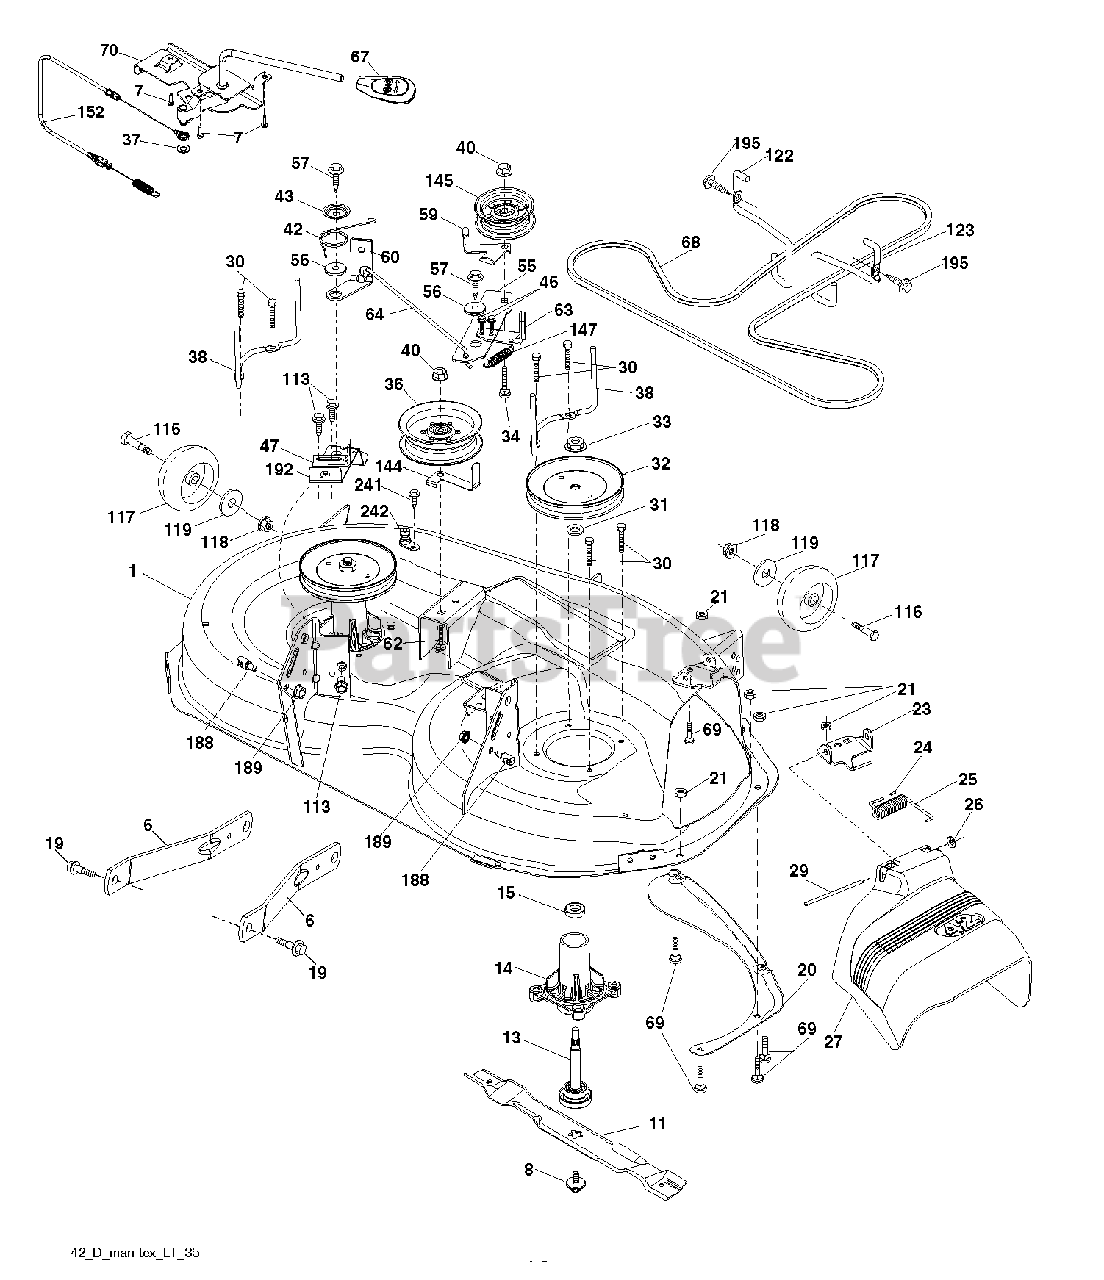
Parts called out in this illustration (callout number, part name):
1	DECK.WELDMENT.42"
6	ARM.SUSPENSION.MOWER.R
7	SCREW.#10 X 0.750.BOS THREAD
8	BOLT.WASHER.ASM.7/16-2
11	42" HI-LIFT BLADE
13	SHAFT.ASM.MDRL.N/GREASE.38
14	HOUSING MANDREL
19	BOLT.SHOULDER
20	BAFFLE.VORTEX
21	LOCKNUT
23	BRKT.DEFLECTOR.38"2005+
24	CAP-SLEEVE LT
25	SPRING.TORSION.DEFLECT
26	NUT PUSH M
27	SHIELD.DEFLECTOR.MOWER.42"BLAC
29	ROD.HINGE
30	SCREW, WASHER HEAD
31	WASHER.SPACER.MANDREL
32	PULLEY.MANDREL.5.438.PD
33	NUT.FLANGE.LOCK.TOP
34	BOLT.3/8-16X1.50
36	PULLEY.IDLER.48"PRIMARY
38	KEEPER.BELT.LH.MANDREL
40	NUT LOCK FLG 3/8-16 UNC
42	SPRING.TORSION.BRAKE
43	SRPING.TORSION.RETAINE
46	SCREW.1/4-20X5/8
47	BRKT.CLUTCH.CABLE
55	IDLER.ARM.42"
56	SPACER.RETAINER
57	SCREW 3/8-16X1
59	GUARD, BELT
60	ARM BRAKE MOWER
62	BOLT
63	ARM BRAKE MOWER
64	LINK BRAKE
67	HANDLE.CLUTCH.CABLE.LT
68	BELT.DECK.DRIVE.42"
69	BOLT
70	CLUTCH.ASM.MANUAL.LT.TEX
113	BOLT.5/16HEX.WHS.HD
117	WHEEL.GAGE.HALF.SPOKED
118	NUT LOCK FLG 3/8-16 UNC
119	WASHER
122	KEEPER BELT ENGINE LH
123	KEEPER BELT RH
144	KEEPER.BELT.MOWER
145	PULLEY.IDLER.2006
147	RETURN SPRING
152	CLUTCH CABLE
188	STUD.FASTNER.W/ANTI-ROTATE
189	NUT LOCK HEX FLANGE 5/16-18
192	BRKT.BRAKE.STAND.LH.
195	SCREW, 3/8-16X3/4
242	PORT.WASHOUT
